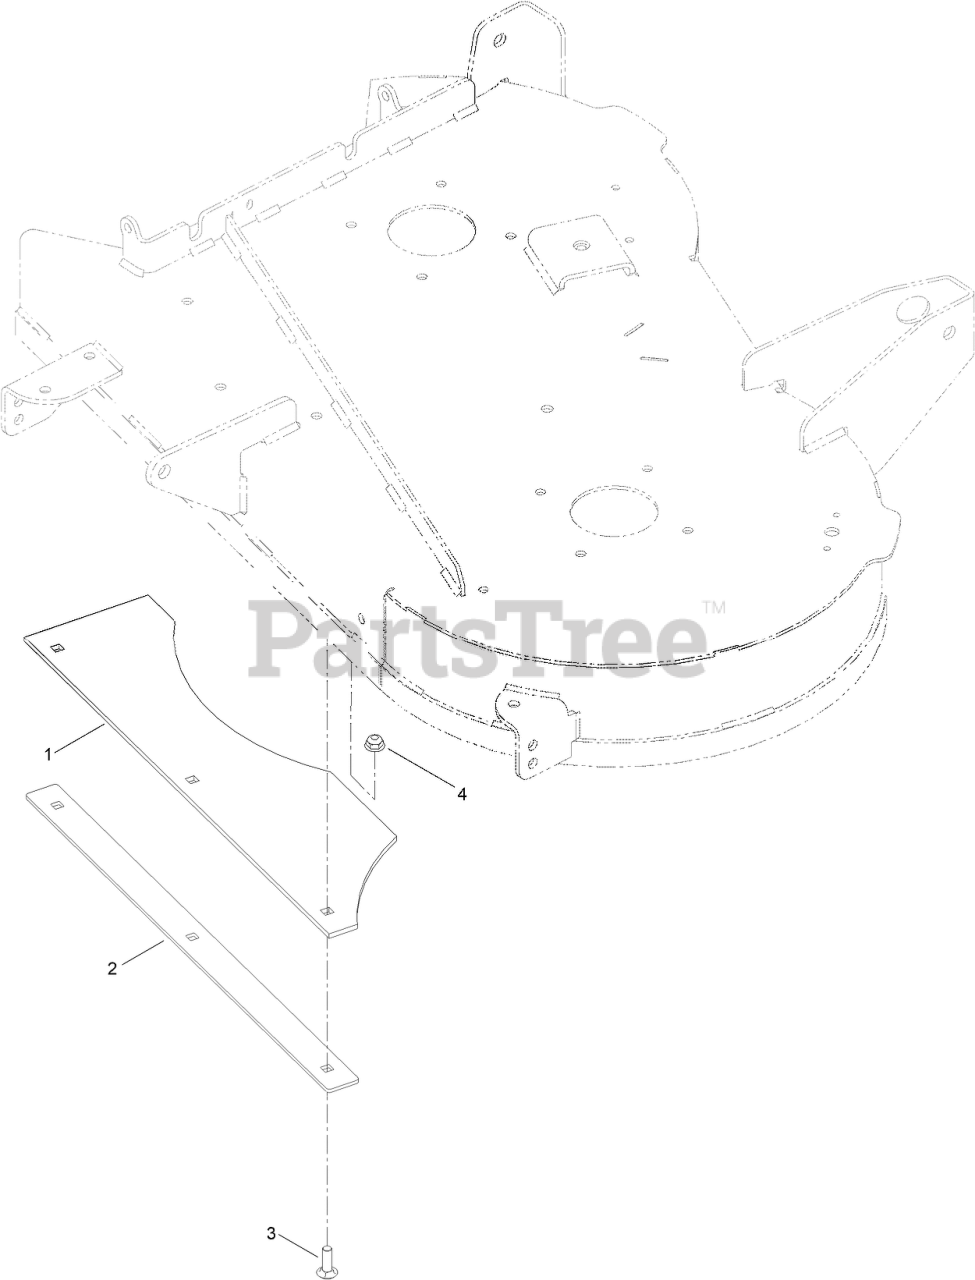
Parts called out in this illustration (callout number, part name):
1	SKIRT-RUBBER
2	PLATE-SKIRT
3	SCREW-CARR
4	NUT-HF
